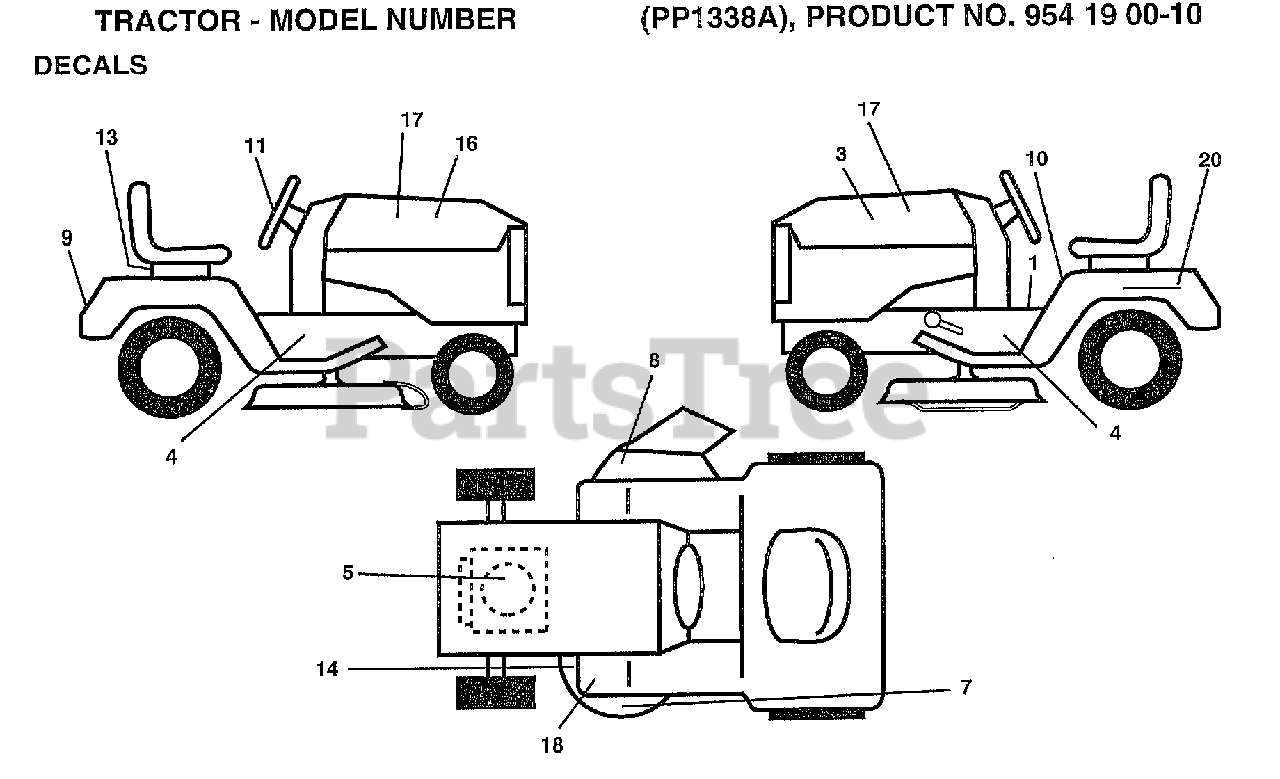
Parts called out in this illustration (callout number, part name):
1	"DECAL.OPER,SDL"
3	"DECAL HOOD,LH"
4	"DECAL CHASSIS,POU"
5	DECAL ENGINE
7	"DECAL,ENVIRO DECK"
8	"DECAL, WARNING"
9	DECAL, FENDER
10	DECAL.CAUT.ENG/FR
11	DECAL, SCL COLD START HYD
13	RETAINER-SPRING
14	DECAL
16	"DECAL HOOD,RH"
17	DECAL DOMED
18	DECAL T
20	DECAL.BATRY.3-3908
